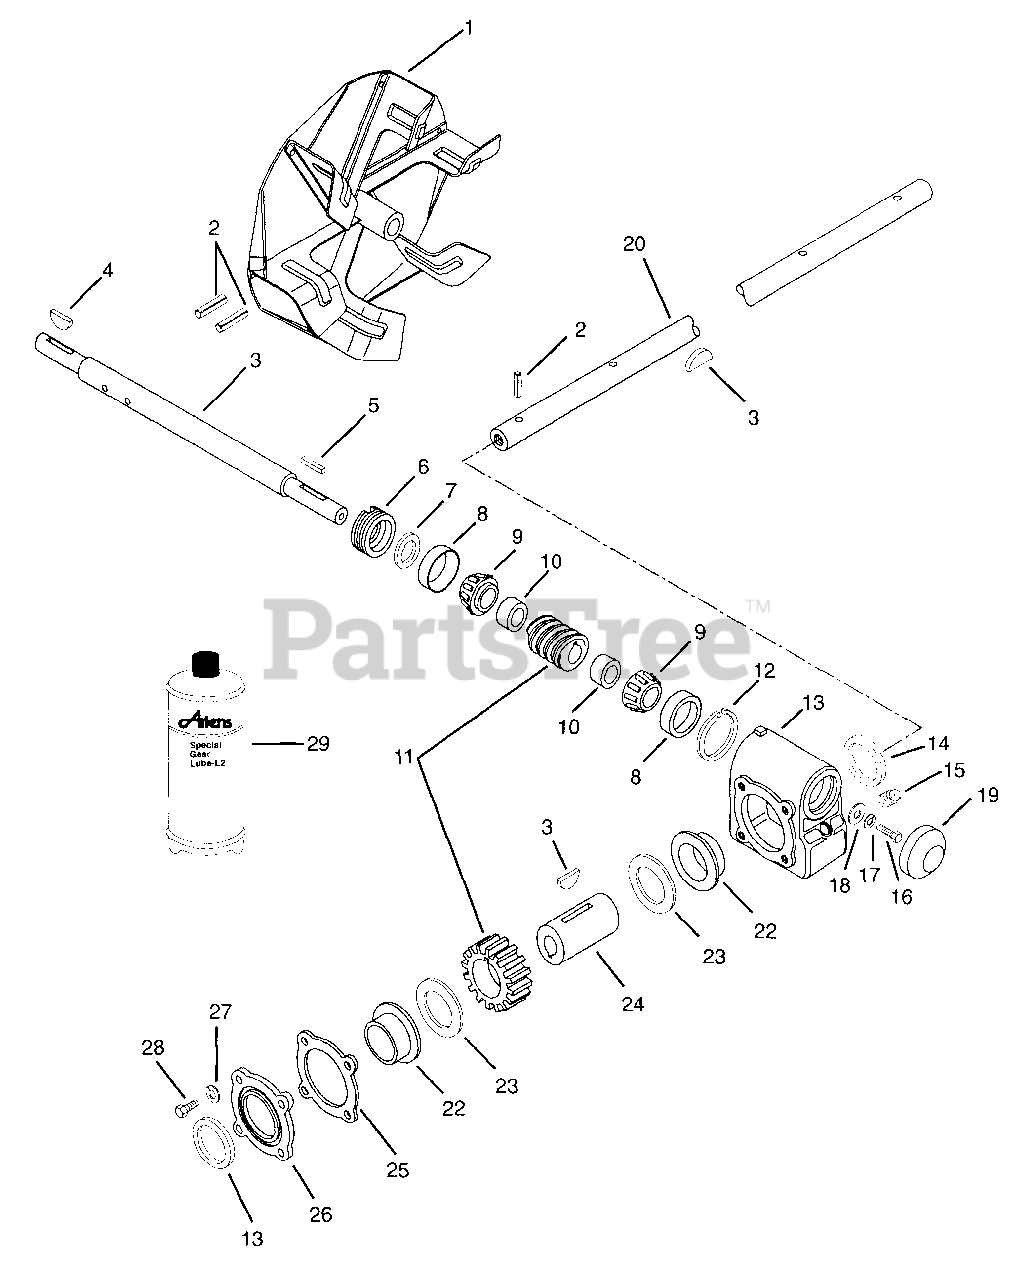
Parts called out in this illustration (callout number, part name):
1	FAN - 14"
2	PIN-ROLL .313X1.75
3	WORM SHAFT
4	KEY-WDRF .25X.875X.375 SAE A
5	KEY-SQ .188X1.0X.188 SAE 8630
6	ADJUSTMENT PLUG - 1" SHAFT
7	SEAL 1.000X1.312X.150
8	BRG-CUP 1.781X.475
9	BRG-CONE .750X.61
10	BSHG, SPCR .755X1.12X.50 PM
11	WORM & GEAR SERVICE ASSEMBLY
12	RG-RTNG-INT 1.781X.062
13	GEAR CASE - CAST IRON
14	SEAL 1.625X2.125X.250
15	PIPE PLUG
16	@BLT-HEX .31-18X.75 GR5 YWZC
17	@WSHR-LK .31X.078 REG YWZC
18	WSHR-FL-STL .328X1.0X.094 YWZC
19	DUST CAP
20	SHAFT, RAKE - 40"
20	SHAFT, 36" RAKE - 1.00 DIA.
21	PIN-ROLL .188X1.50
22	BSHG-FLG .683X1.87X1.68X2.250
23	WSHR-FL-STL 1.625X2.500X.012
24	GEAR CASE SHAFT
26	GEAR CASE COVER
27	@WSHR-LK-EXT.262X.502X.026YWZC
28	@BLT-HEX .25-20X.75 GR5 YWZC
29	ARIENS 16 OZ.BOTTLE OF L2 LUBE
